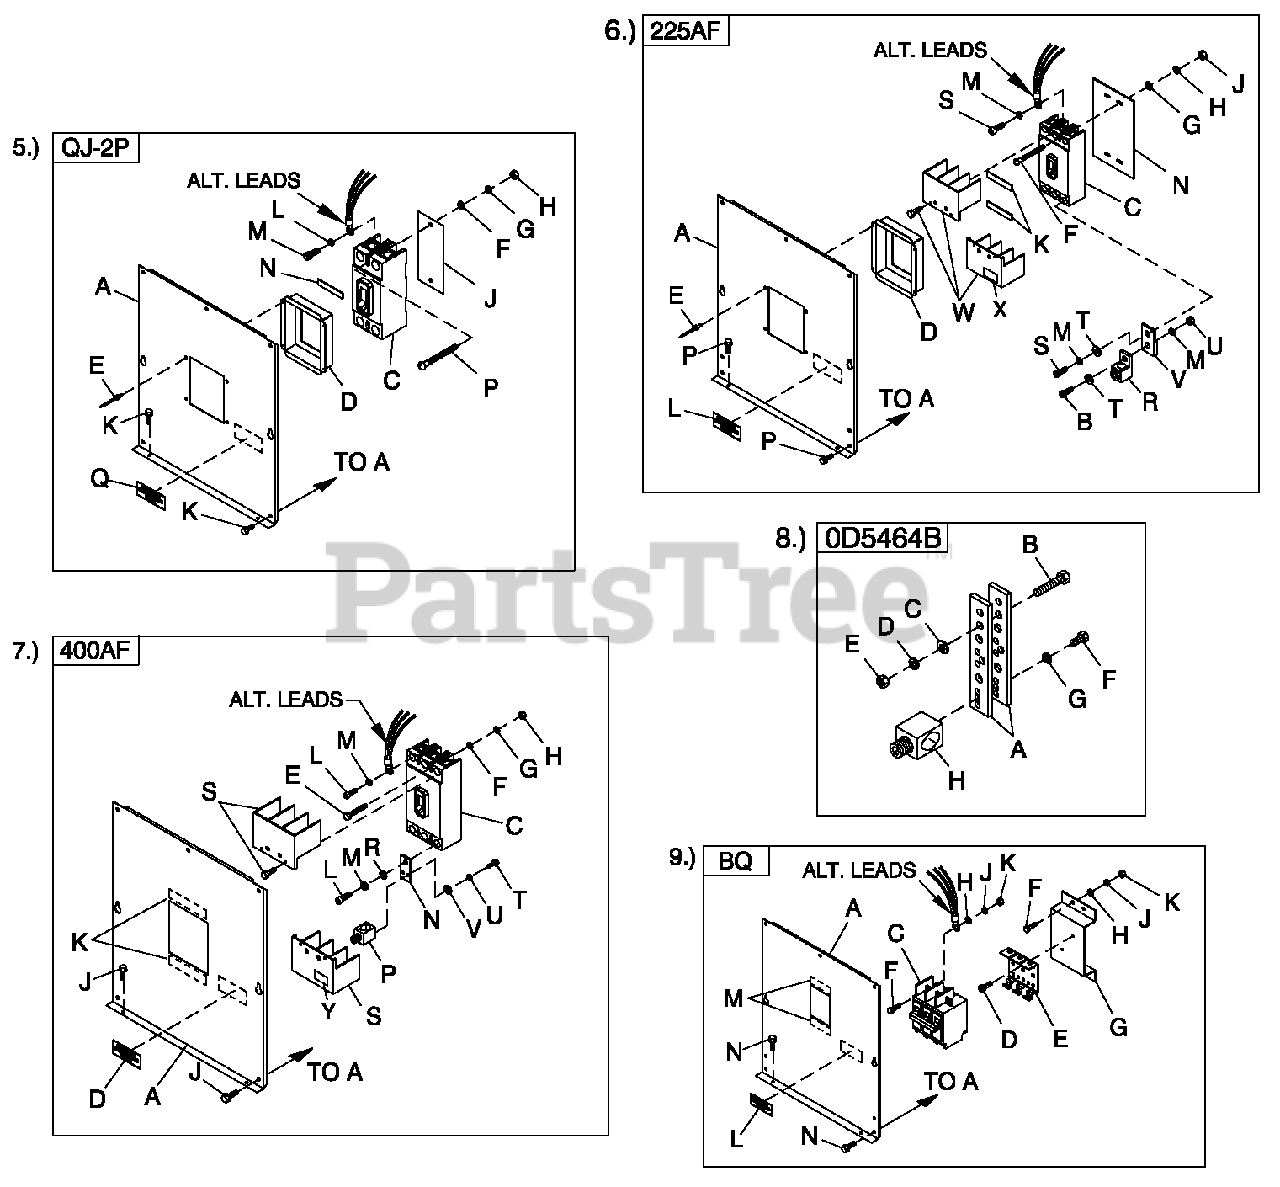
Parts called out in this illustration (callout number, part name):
9	UL CIRCUIT BREAKER (BQ)
A	COVER QJ 2P FRMCB
C	CB 0225A 240V 2P S QJ22
D	COVER QJ 2P CB DISH
E	RIVET POP .125 X .275 SS
F	WASHER FLAT 1/4-M6 ZINC
G	WASHER LOCK M6-1/4
H	NUT HEX 1/4-20 STEEL
J	INSULCB2PQJ
K	SCREW THF M6-1 X 16 N WAZ/JS
L	WASHER LOCK 3/8
M	SCREW SHC 3/8-16 X 3/4 G8.8 NZ
N	TAPE ELEC 1/2 FOAM (AS REQ'D)
P	SCREW RHM 1/4-20X3
Q	DECAL CUSTOMER CONNECT INSIDE
A	COVER CB C2-C4 (225AF)
B	SCREW SHC M8-1.25 X 25 G12.9
C	CIRCUIT BREAKERS 200A FRAME (3P)
D	COVER CB DISH 225AF (3P)
F	SCREW RHM #8-32X3-1/4
G	WASHER FLAT #8 ZINC
H	WASHER LOCK #8-M4
J	NUT HEX #8-32 STEEL
K	TAPE ELEC 1/2 FOAM
L	DECAL CUSTOMER CONNECT INSIDE
M	WASHER LOCK M8-5/16
N	INSULATOR CB225AF(3P)
P	SCREW THF M6-1 X 16 N WAZ/JS
R	LUG SLDLSS 300 MCM-6 AL/CU
S	SCREW SHC M8-1.25X 20G8
T	WASHERFLAT 5/16-M8ZINC
U	NUT HEX M8-1.25 G8 CLEAR ZINC
V	BUS BAR 200A LUG ADAPTOR
W	TERMINAL COVER CB
X	DECALTERMINALSHOCK HZD BI
A	COVER CB C2-C4 400AF
C	CIRCUIT BREAKERS 400A FRAME
D	DECAL CUSTOMER CONNECT INSIDE
E	SCREW RHM 1 0-3 2X4
F	WASHER FLAT #10 ZINC
G	WASHER LOCK #10
H	NUT HEX #10-32 STEEL
J	SCREW THF M6-1 X 16 N WAZ/JS
L	SCREW SHC M10-1.5X25G12.9
M	WASHER LOCK M10
N	BUS BAR CB ADAPTER 225-400 A
P	LUG SLDLSS 600/250-1/0 X 1/4-28
S	TERM COVER CB
T	SCREW HHC 1/4-28 X 1/2 G5
U	WASHER LOCK M6-1/4
V	WASHERFLAT 1/4-M6 ZINC
W	SCREW SHC M10-1.5X25G12.9
X	WASHER LOCK M10
Y	DECAL TERMINALSHOCK HZD BI
A	BUS BAR NEUTRAL BLOCK 390
B	SCREW HHC M8-1.25 X 45 G8.8 FT
C	WASHER FLAT 5/16-M8 ZINC
D	WASHER LOCK M8-5/16
E	NUT HEX M8-1.25G8YEL CHR
F	SCREW HHC 1/4-28 X 3/4 G5
G	WASHER LOCK 1/4-M6SS
H	LUG SLDLSS 600/250-1/0 X 1/4-28
A	COVER BQ CIR BREAKER CPL 3P
C	CB0125A2P 240V SBQ2 LL
D	SCREW PHTTM4-0.7X 10 ZYC
E	BRKT CB MTG BACK
F	SCREW RHM #10 -3 2X3 /4
G	BRKT BQCB STANDOFF
H	WASHER FLAT #10 ZINC
J	WASHER LOCK #10
K	NUT HEX #10-32 STEEL
M	TAPE ELEC 1/2 FOAM
N	SCREW THF M6-1 X 16 N WA Z/JS
